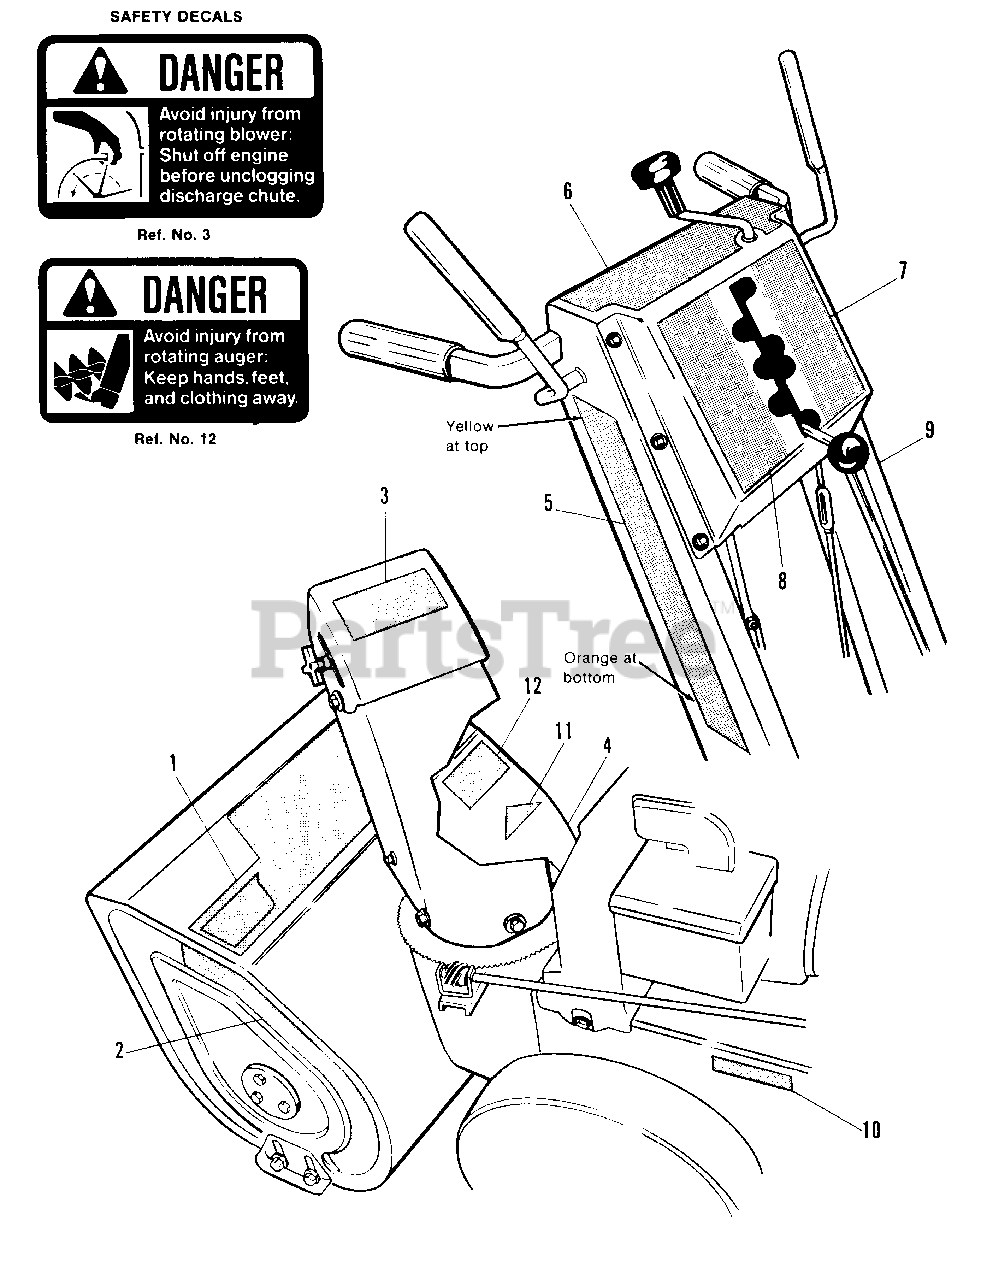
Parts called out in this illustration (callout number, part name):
1	DECAL, Housing, 560
1	DECAL, Housing, 860
1	DECAL, Housing, 870
1	DECAL, Housing, 1070
2	DECAL, Housing, End L.H.
3	DECAL, Danger, Blower
4	DECAL, Hsg., End, R.H.
5	DECAL, Handle, R.H.
6	DECAL, Dash
7	DECAL, Shift Pattern, L.H.
8	DECAL, Shift Pattern, R.H.
9	DECAL, Handle, L.H.
10	I.D. Tag
11	DECAL, OPEI
12	DECAL, Danger, Auger
